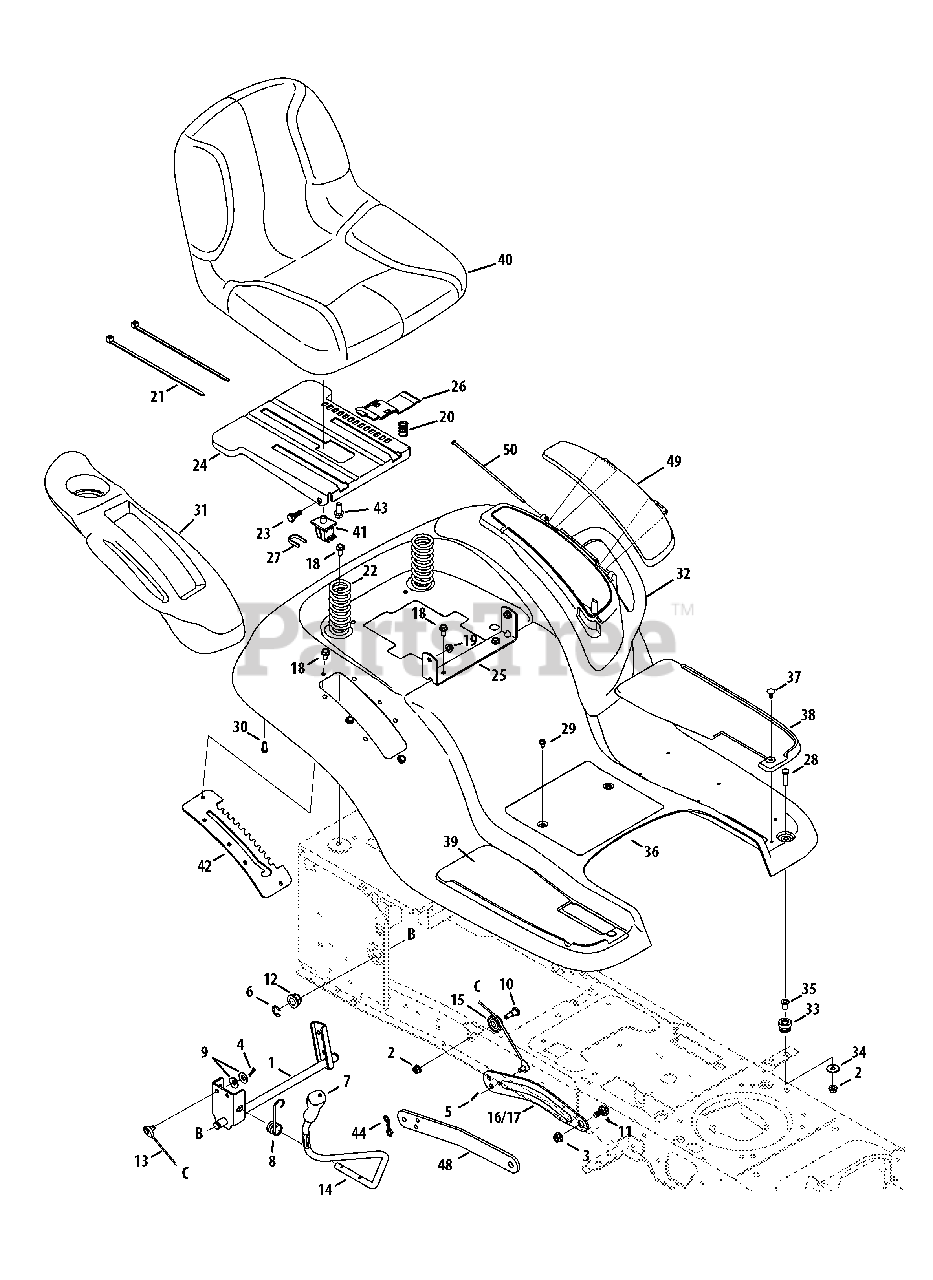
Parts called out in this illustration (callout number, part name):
1	Shaft Ass’y, Lift
2	Nut, Flange Lock, 5/16-18, Grf
3	Nut, Flange Lock, 3/8-16, Grf
4	Pin, Cotter, .072 Dia. x 1.13
5	Pin, Cotter, Bow-Tie 72 (42")
6	Ring, E Type, .625 Dia. Shaft
7	Grip, Handle, Cub, .50 ID
8	Spring, Torsion
9	Washer, Spring, .401 x .870 x .063
10	Screw, Shoulder, .437 x .470, 5/16-18
11	Bolt, Shoulder, .625, 3/8-16 (42")
12	Bearing, Hex Flange
13	Cable, Lift, 16.16
14	Handle, Lift,
15	Pulley, Roller, Cable
16	Arm, Lift, RH (42")
17	Arm, Lift, LH (42")
18	Screw, Self-tapping, 5/16-18, .750,
19	Nut, Flange Lock, 5/16-18, Gr5, Sd Lk
20	Spring, Comp, .68 x 1.065 x .055
21	Cable, Tie, 3/16 x .05 x 7.4
22	Spring, Comprs, 1.50 x 3.90 x .200
23	Screw, Shoulder, .437 x .268, 5/16-18
24	Bracket, Mounting, Seat
25	Bracket, Pivot, Seat
26	Lever, Seat Adjustment
27	Clip, Retaining, Switch
28	Hex Screw, 5/16-18, 1.25, Gr5, Std
29	Screw, Self-tapping, 1/4-20, 0.500
30	Screw, HL, 1/4-15, 0.750
31	Cover, Fender, RH
32	Cover, Fender, LH
33	Grommet, .4375 ID x .750
34	Washer, Flat .344 x 1.00 x .063
35	Spacer, Flange, .3125 x .4375 x .625
36	Fender, Cub Hydro
37	Clip, Ratchet, .250 Dia
38	Pad, Foot, LH
39	Pad, Foot, RH
40	Seat, High Back Cloth, Cub
41	Switch, Seat
42	Bracket, Lift, Manual PTO, 12 Pos
43	Hex Flange Bolt, 3/8/16, .875, Gr5
44	Pin, Cotter, Bow-Tie 72 (46")
48	Link, Lift (46")
49	Door, Cover, Fender
